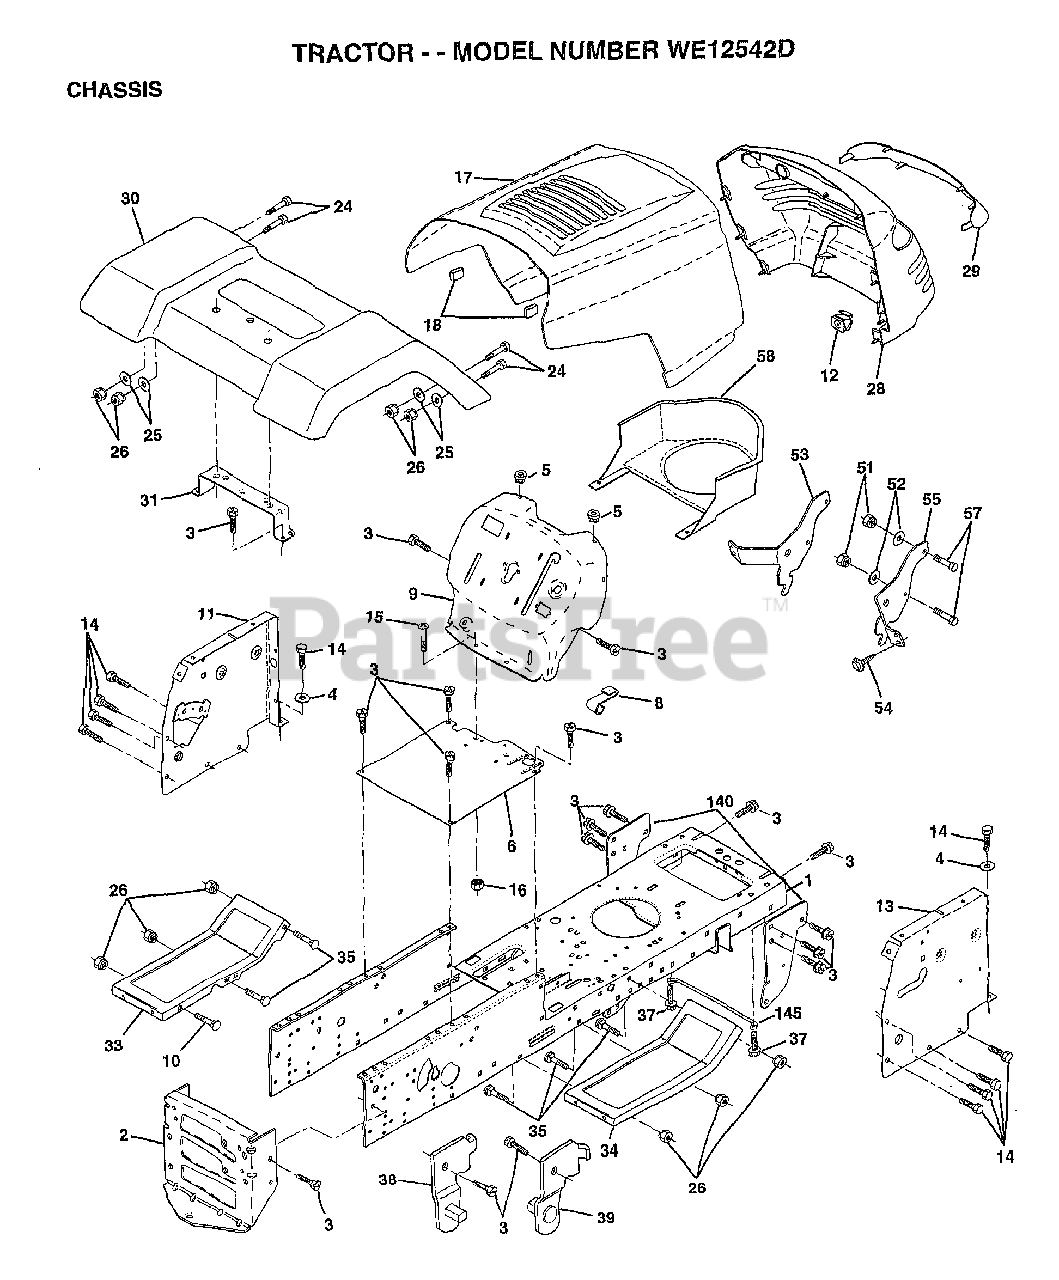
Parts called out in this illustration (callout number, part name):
3	SCREW
4	WASHER
5	BUMPER-HOOD/DASH
6	SADDLE-SILKSCREEN
8	CLIP.RETAINER
9	DASH SILKSCREEN
11	"PANEL-DASH,LH"
12	CLIP.TINNERMAN
14	SCREW LT
15	SCREW
17	HOOD.STEEL.ASSY
24	BOLT
25	WASHER
26	NUT
28	GRILLE-MS428
29	LENS.GRILLE.PRIVATE LABEL
30	FENDER PNT LT
31	BRKT FENDER
33	FOOTREST.LH.PERF.
34	FOOTREST.RH.PERF.
35	BOLT
37	SCREW LT
38	BRACKET ASM LH
39	BRACKET ASM RH
51	NUT
52	WASHER
53	BRACKET.GRILLE.LH
54	SCREW.HEX.WS.HD
55	BRACKET.GRILLE.RH
58	AIR DUCT
140	BRKT SUSPENSION
145	"ROD POVOT,CHASSIS"
